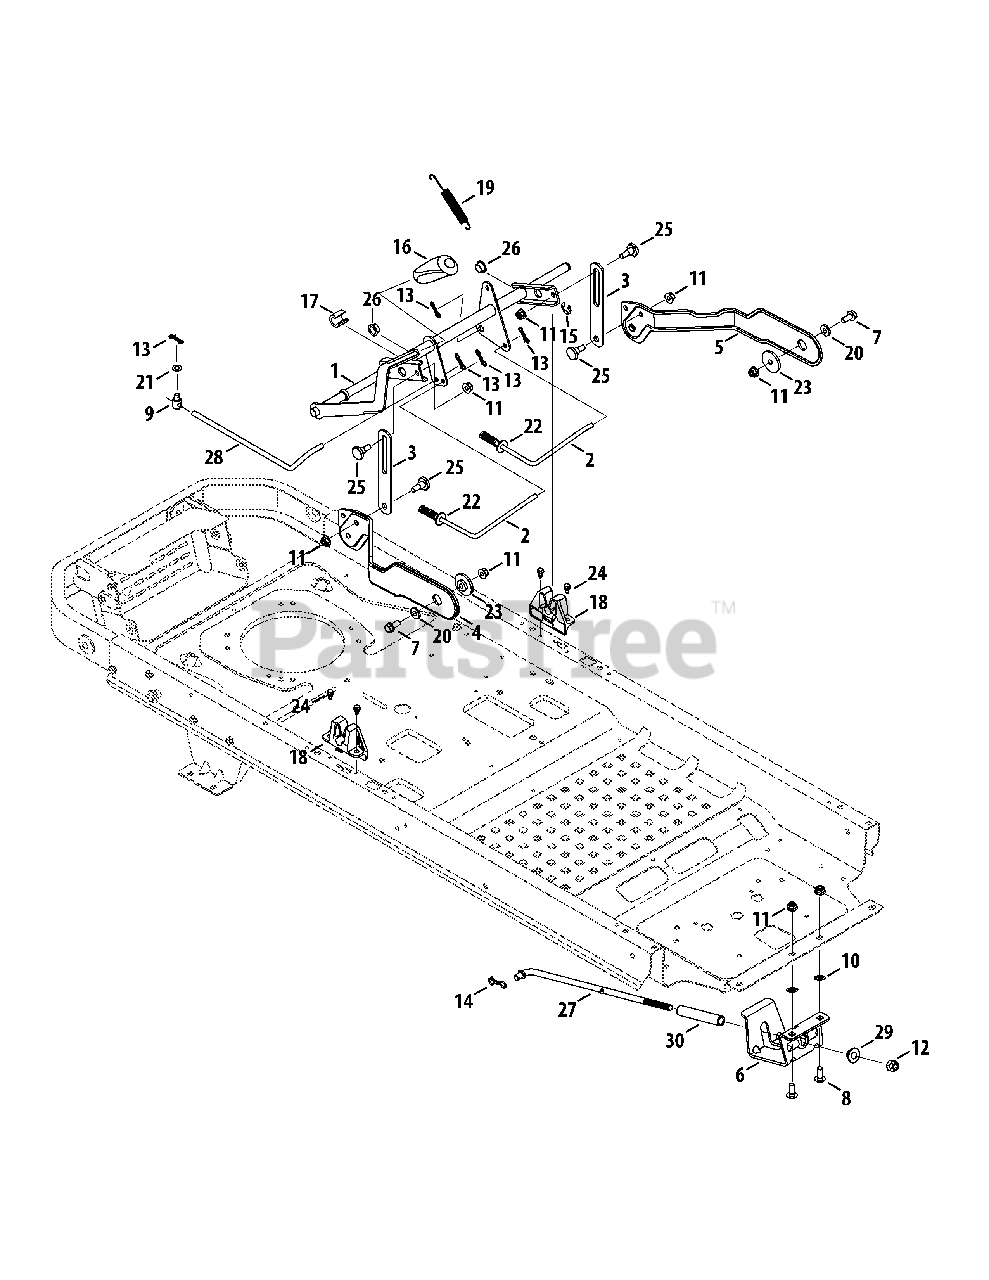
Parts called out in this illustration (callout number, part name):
1	Deck Lift Shift Assembly
2	Brake Rod Assembly, w/spring
3	Lift Link Plate
4	Deck Lift Plate, RH
5	Deck Lift Plate, LH
6	Rod Support Mounting Bracket
7	Hex Screw, 3/8-16 x 1.25
8	Carriage Bolt, 3/8-16 x 1.00
9	Ferrule, 3/8-24 x .375
10	Push Nut, 3/8
11	Flange Lock Nut, 3/8-16
12	Flange Lock Nut, 1/2-13
13	Bow-Tie Cotter Pin
14	Bow-Tie Cotter Pin
15	E-Type Ring, .750
16	Grip, .50 ID
17	Spacer, .76 ID x .750 LG
18	Deck Lift Bracket
19	Extension Spring, .63 Dia. x 4.95 LG
20	Flat Washer, .385 x .870 x .092
21	Washer, .375 x .700 x .030
22	Flat Washer, .344 x 1.00 x .063
23	Shoulder Spacer, .884 x .190
24	Shoulder Screw, .500 x 1/4-20
25	Shoulder Screw, .500 Dia. x .434
26	Flange Bearing, .751 x 1.125 x .375
27	Deck Lift Rod
28	Brake Rod
29	Deck Lift pivot Cup
30	Nylon Sleeve, .55 ID x 4.50 LG
